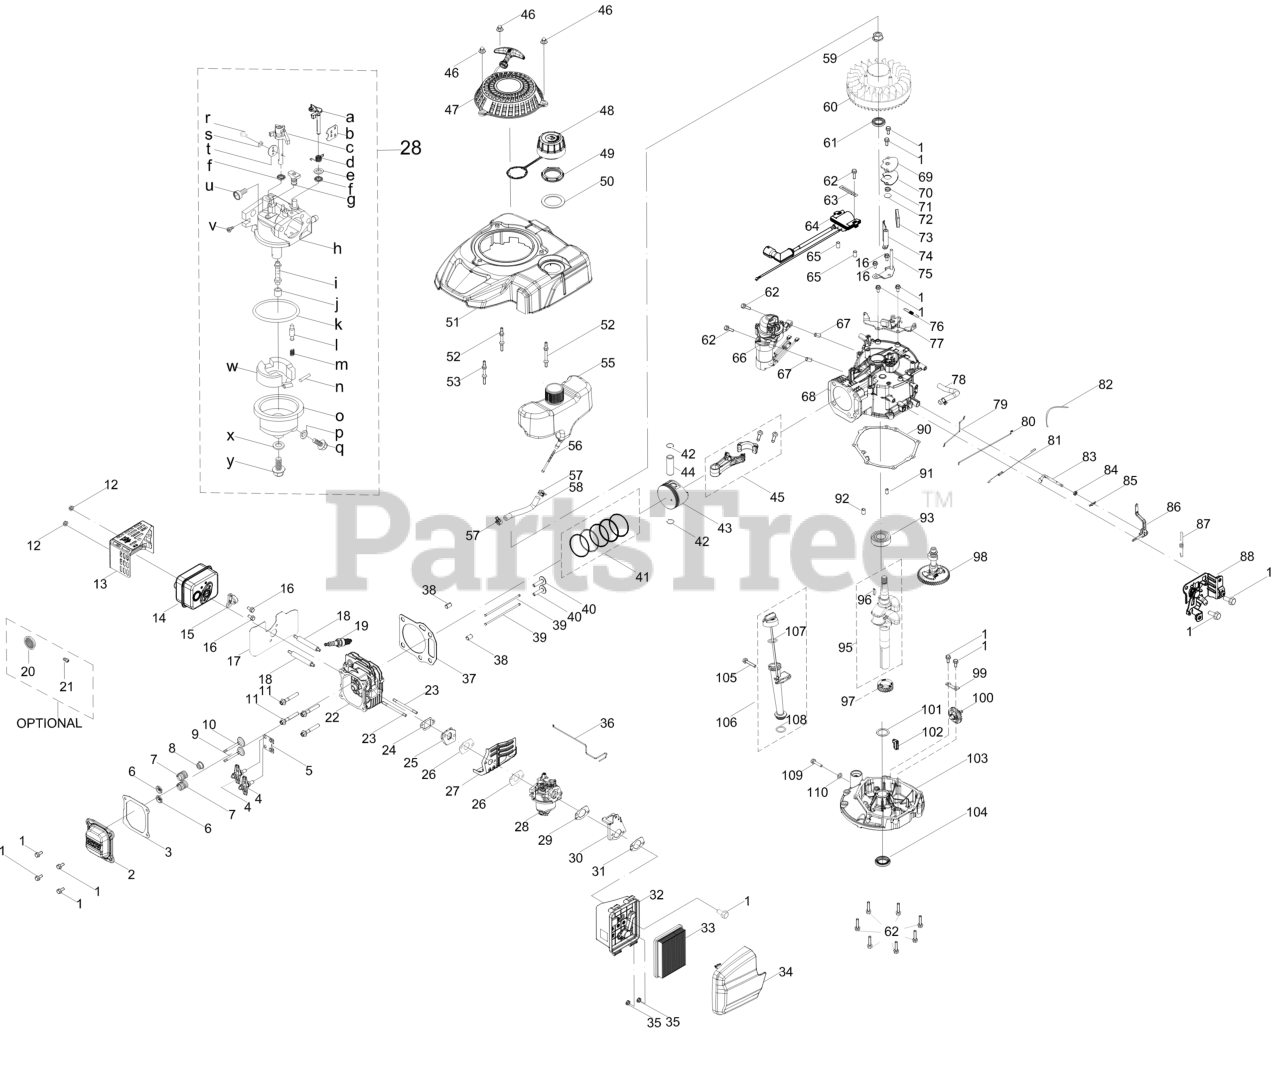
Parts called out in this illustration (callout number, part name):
1	BOLT M6-1 x 14 GR8.8
2	VALVE COVER
3	VALVE COVER GASKET
4	ROCKER ARM ASSEMBLY
5	PUSH ROD GUIDE
6	VALVE SPRING RETAINER
7	VALVE SPRING
8	INTAKE VALVE SEAL
9	EXHAUST VALVE
10	INTAKE VALVE
11	BOLT-M8 x 54
13	MUFFLER SIDE SHIELD
14	MUFFLER ASSEMBLY
15	THERMOSTAT
16	BOLT M6-1 x 12 GR8.8
17	MUFFLER GASKET
18	STUD M6-1 x 98
19	SPARK PLUG
20	SPARK ARRESTOR
21	SCREW M3.5 x 9.5
22	CYLINDER HEAD
23	STUD M6 x 90
24	CARBURETOR INSULATOR GASKET
25	CARBURETOR INSULATOR
26	CARBURETOR GASKET
27	CARBURETOR HEAT SHIELD
28	CARBURETOR
29	AIR FILTER BRACKET GASKET
30	AIR FILTER BRACKET
31	AIR FILTER BASE GASKET
32	AIR FILTER BASE
33	AIR FILTER
33	Cub Cadet AIR FILTER
33	Genuine Factory Parts AIR FILTER
34	AIR FILTER COVER
36	CHOKE TEMP CONTROL LINKAGE
37	CYLINDER HEAD GASKET
40	TAPPET
41	PISTON RING SET
42	SNAP RING-PISTON PIN
43	PISTON
44	PISTON PIN
45	CONNECTING ROD ASSEMBLY
46	ACORN NUT
47	RECOIL STARTER ASSEMBLY
48	FUEL CAP W/TETHER
49	FUEL TANK NUT
50	FUEL TANK UPPER GROMMET
51	ENGINE SHROUD W/O IGNITION SWITCH
52	STARTER/SHROUD REAR STUD
53	STARTER SHROUD FRONT STUD M6X74
55	FUEL TANK
56	FUEL FILTER
56	Genuine Factory Parts FUEL FILTER
57	HOSE CLAMP
58	FUEL HOSE
59	FLYWHEEL NUT
60	FLYWHEEL ASSEMBLY
61	CRANKSHAFT SEAL
62	BOLT-M6-1 x 28 GR8.8
63	FLEXIBLE CLAMP
64	IGNITION COIL ASSEMBLY
65	IGNITION COIL SPACER
66	ELECTRIC STARTER ASSEMBLY
67	DOWEL PIN
68	CRANKCASE
69	BREATHER COVER PLATE
70	BREATHER GASKET
71	BREATHER VALVE SPRING
72	BREATHER VALVE
73	BREATHER SCREEN
74	AIR VANE
75	AIR VANE BRACKET
76	ENGINE BRAKE SPRING
77	ENGINE BRAKE ASSEMBLY
78	BREATHER HOSE ASSEMBLY
79	CHOKE LINKAGE
80	THROTTLE LINKAGE
81	THROTTLE LINKAGE SPRING
82	CABLE TIE - 3 x 150
83	GOVERNOR ARM SHAFT
84	GOVERNOR SEAL
85	COTTER PIN
86	GOVERNOR ARM ASSEMBLY
87	GOVERNOR SPRING
88	TWO SPEED THROTTLE CONTROL
90	CRANKCASE COVER GASKET
91	DOWEL PIN
92	DOWEL PIN
95	CRANKSHAFT
96	FLYWHEEL KEY
97	CRANKSHAFT TIMING GEAR
98	CAMSHAFT ASSEMBLY
99	GOVERNOR GEAR MOUNTING PLATE
100	GOVERNOR GEAR/SHAFT ASSEMBLY
101	THRUST WASHER
102	OIL RETURN SEAL
103	CRANKCASE COVER
104	LOWER CRANKSHAFT SEAL
105	BOLT M6-1 x 35 GR8.8
106	OIL DIPSTICK ASSEMBLY
107	O-RING
109	OIL DRAIN PLUG
110	WASHER
S	Throttle Plate Lock Washer
